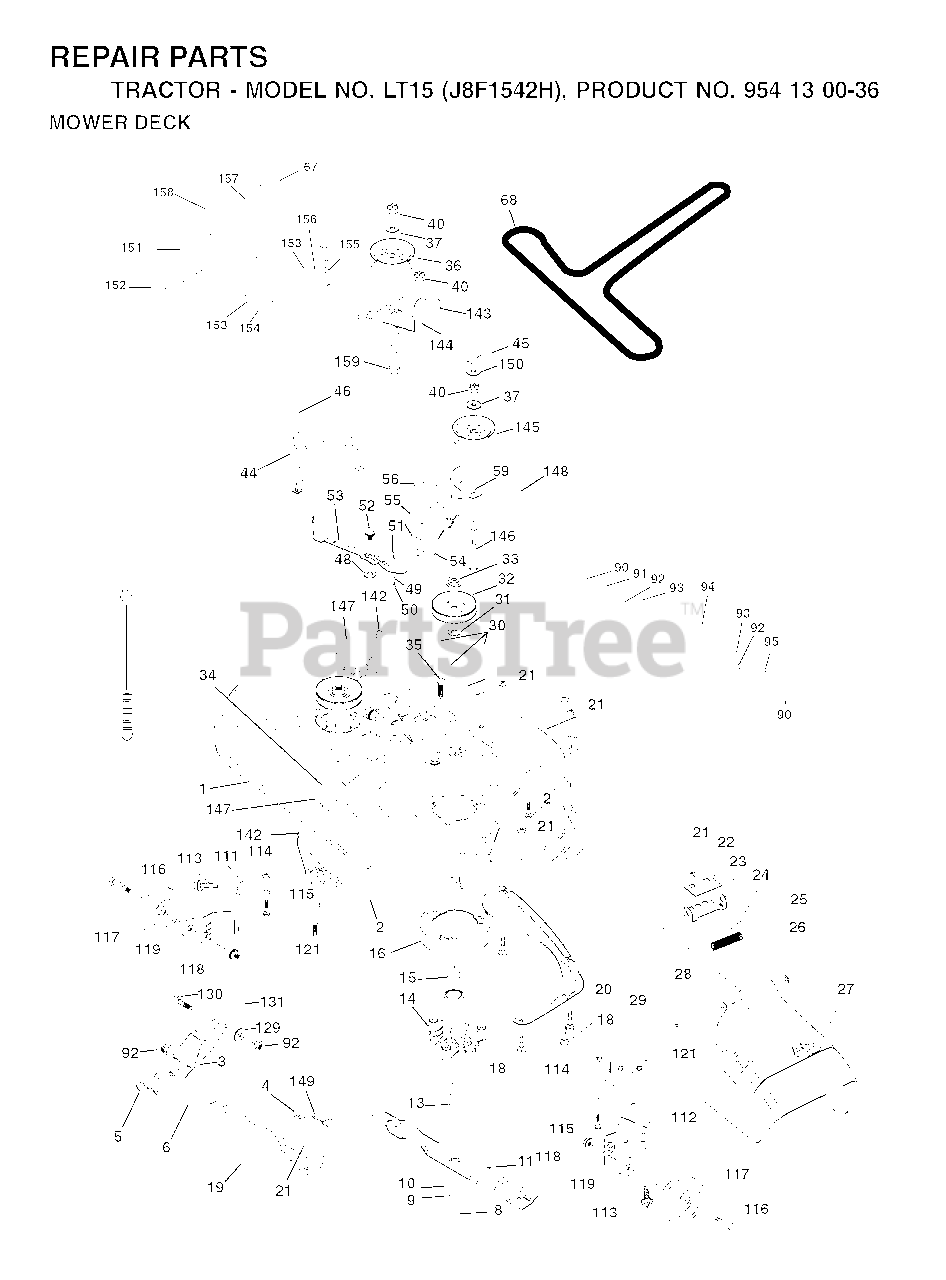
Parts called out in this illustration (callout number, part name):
1	42" DECK KIT
2	BOLT
3	BRKT ASM SWAY BAR
4	BRACKET SWAY BAR 42" DECK
5	RETAINER-SPRNG RB
6	REAR SUSP ARM
8	BLADE BOLT
9	LOCKWASHER
10	WASHER.BLADE
11	BLADE 42"
13	SHAFT ASM VENT
14	HSG MANDREL
16	STRIPPER
18	BOLT
19	BOLT SHD 5/16-18
20	BAFFLE.VORTEX
21	LOCKNUT
22	STIFFENER BRACKET
23	DEFLECTOR BRACKET
24	CAP-SLEEVE LT
25	SPRING TORSION
26	NUT PUSH M
27	SHIELD DEFLECTOR
28	WASHER
29	ROD.HINGE
30	SCREW THDROL ROLLING WASHER HD
31	WASHER
32	PULLEY/MANDREL
33	NUT
34	BOLT
35	FASTENER.XMAS.TREE
36	FLAT IDLER PULLEY
40	LOCKNUT
44	GUARD MANDREL LH BLACK
45	RETAINER M
46	SCREW.1/4-20X5/8
49	ROLLER ASM CAM FOLLOWER
50	BOLT
53	ARM
54	HARDENED WASHER
55	ARM IDLER 42" MOWER LT/YT
56	SPACER.RETAINER.MOWER
59	GUARD, BELT
67	KNOB T (3/8 HOLE)
68	BELT V SECONDARY
90	BOLT
91	BRACKET LH (A)
92	NUT
94	NOSE ROLLER
95	BRACKET RH (B)
111	BRACKET WHEEL GAUGE LH 42" DK
112	BRACKET WHEEL GAUGE RH 42" DK
114	NUT
115	BOLT
117	WHEEL.GAUGE.STANDARD
118	LOCKNUT
119	WASHER
121	BRACKET.EXTRD.GWL
129	WASHER
131	BOLT D
142	ARM SPRING BRAKE MOWER
143	BRACKET, ARM IDLER
144	KEEPER.BELT.42".CLUTCH.CABLE
145	PULLEY
146	BOLT, CARRIAGE IDLER BLACK
147	SPRING EXTENSION
148	IDLER RETURN SPRING
149	SPRING.RETAINER.YELLOW.ZINC
150	WASHER PM
151	BRACKET, CLUTCH CABLE
152	CLUTCH CABLE 42"
153	WASHER FLAT 3/8"
154	SPRING RETAINER
155	SPRING RETENTION LEVER
156	SPACER CLUTCH CABLE
157	ROD CLUTCH CABLE 3/8"
158	SCREW LT
159	BOLT
